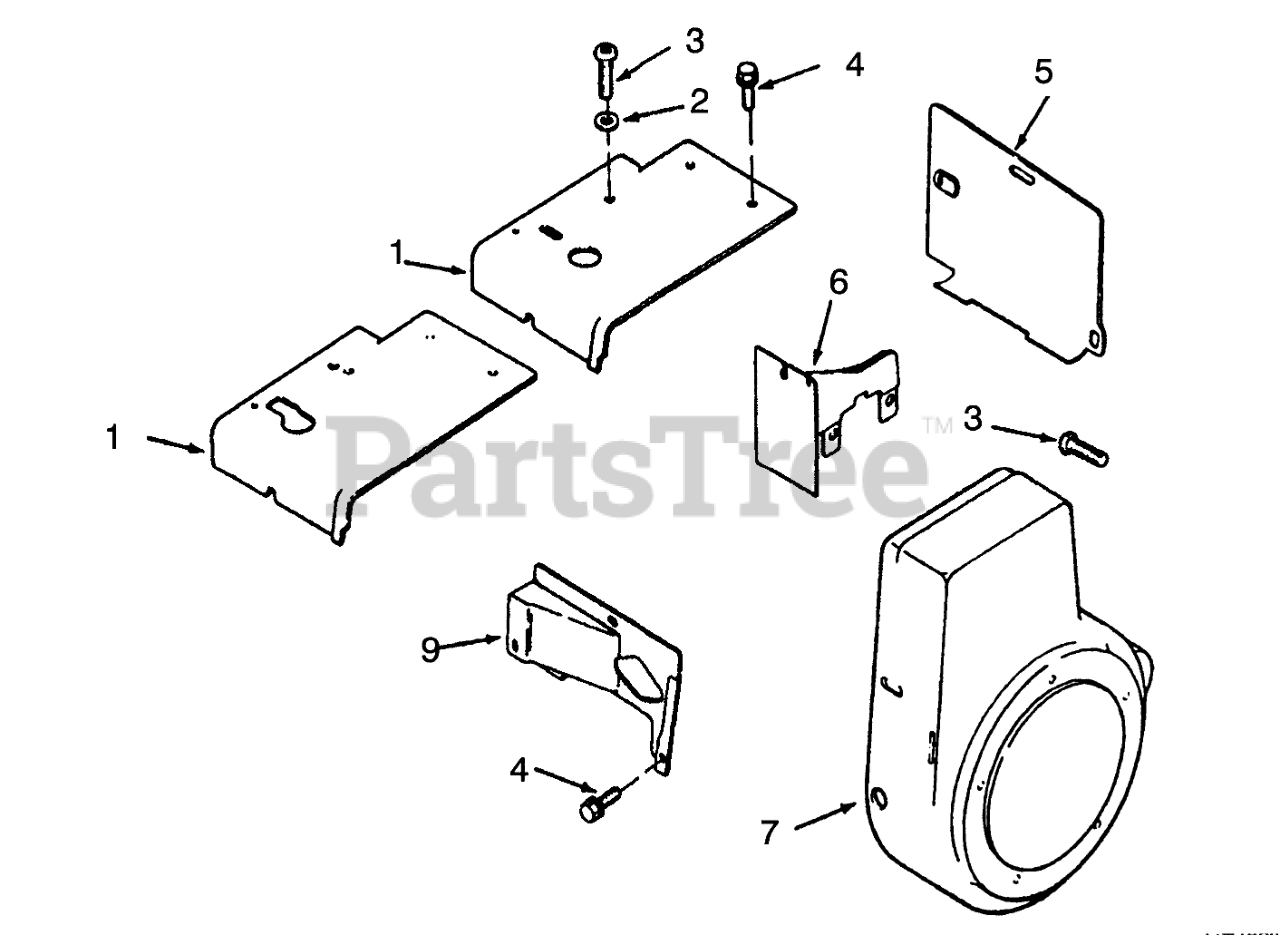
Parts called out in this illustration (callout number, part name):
1	Baffle-Head
2	Washer
3	Screw-Pozidriv T.H.
4	Screw Hex Hd
5	Baffle-Cylinder
6	Baffle-Inner
7	Blower Housing
9	Baffle-SideAir
